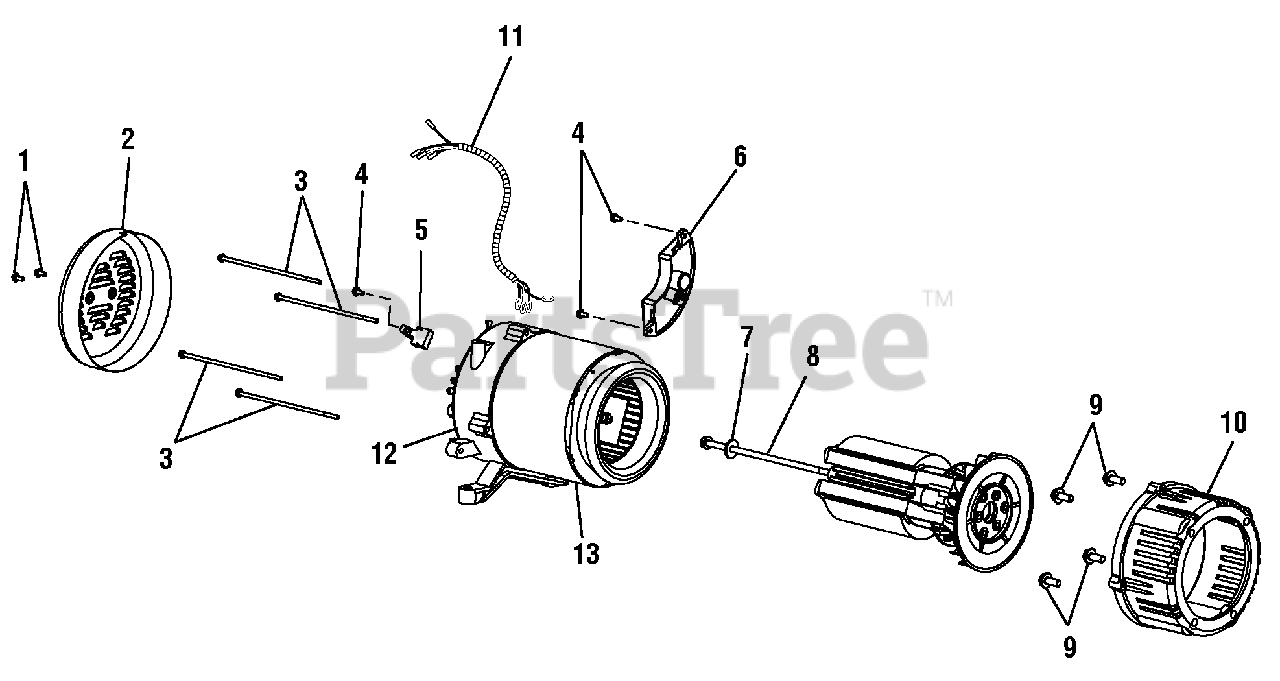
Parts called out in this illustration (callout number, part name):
2	Brush Cover
3	Bolt (M6 x 164 mm)
5	Brush Assembly
6	Automatic Voltage Regulator
7	Washer ( 5/16 in.)
8	Bolt (5/16-24 x 215 mm, Hex. Hd.)
9	Bolt (3/8-18 x 1-1/4 in.)
10	Engine Adaptor
11	Wiring Harness
12	Bearing Support
13	Generator Head Cover
